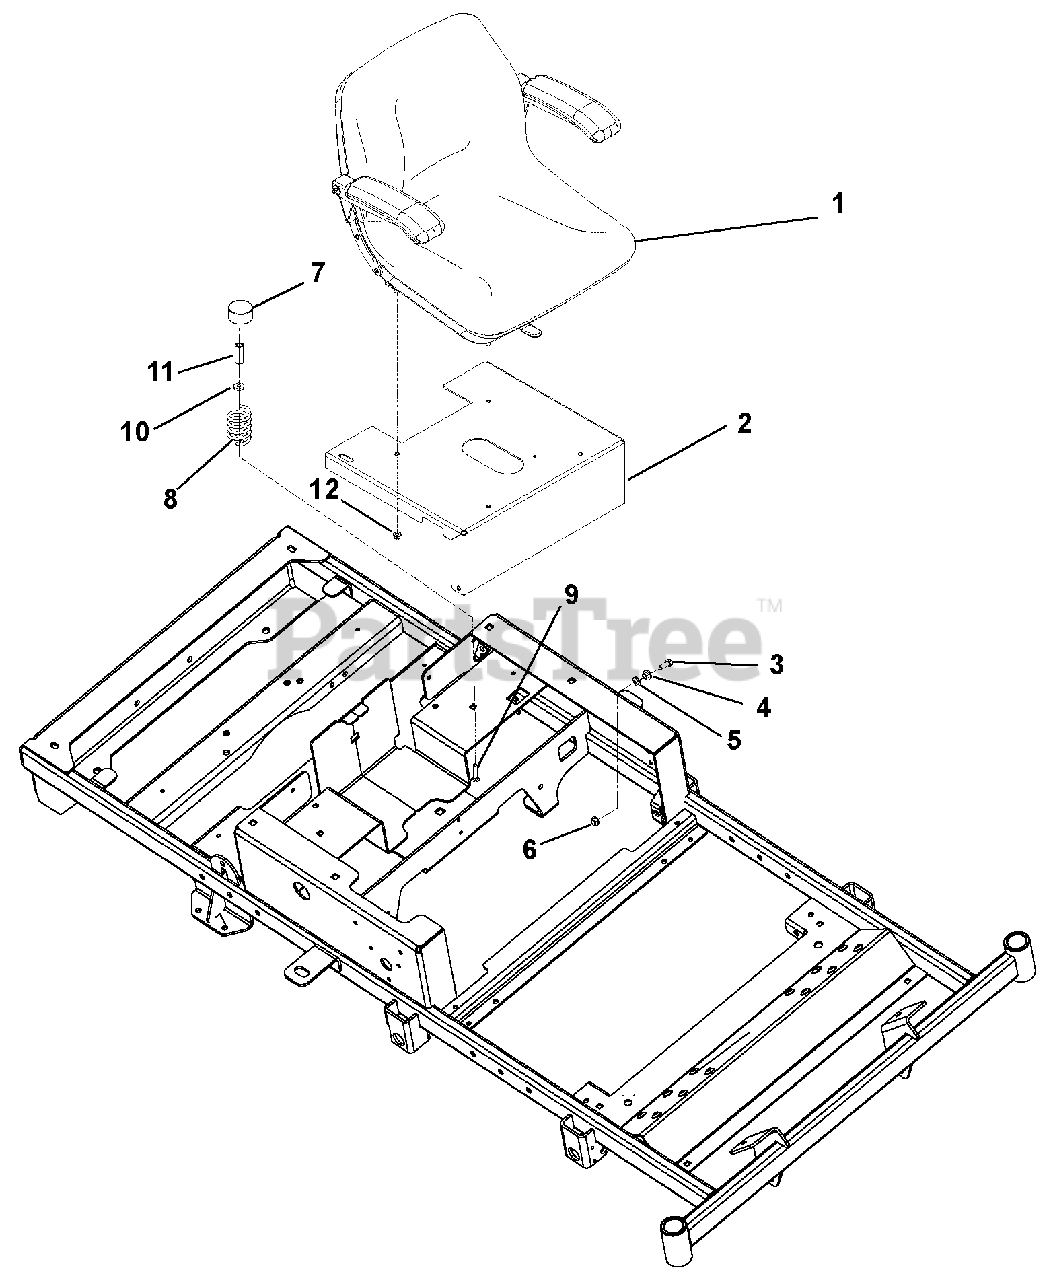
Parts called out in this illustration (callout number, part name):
1	Seat with Armrests
2	Seat Plate
3	Bolt, Hex .38-16 x 1.00 Grade 5
4	Bushing, Flange .385 x .500 x .875 x .406
5	Washer, Flat Steel .52 x .827 x .062
6	Nut, .38-16 Nyloc Flange
8	Spring, Seat
9	Bolt, Round Head Square Neck .31-18 x 1.50 Grade 5
10	Washer, Flat Steel .328 x .87 x .179
11	Nut, Coupling 5/16-18 x 1 .75
12	Nut, 5/16-18 Flange Nyloc
